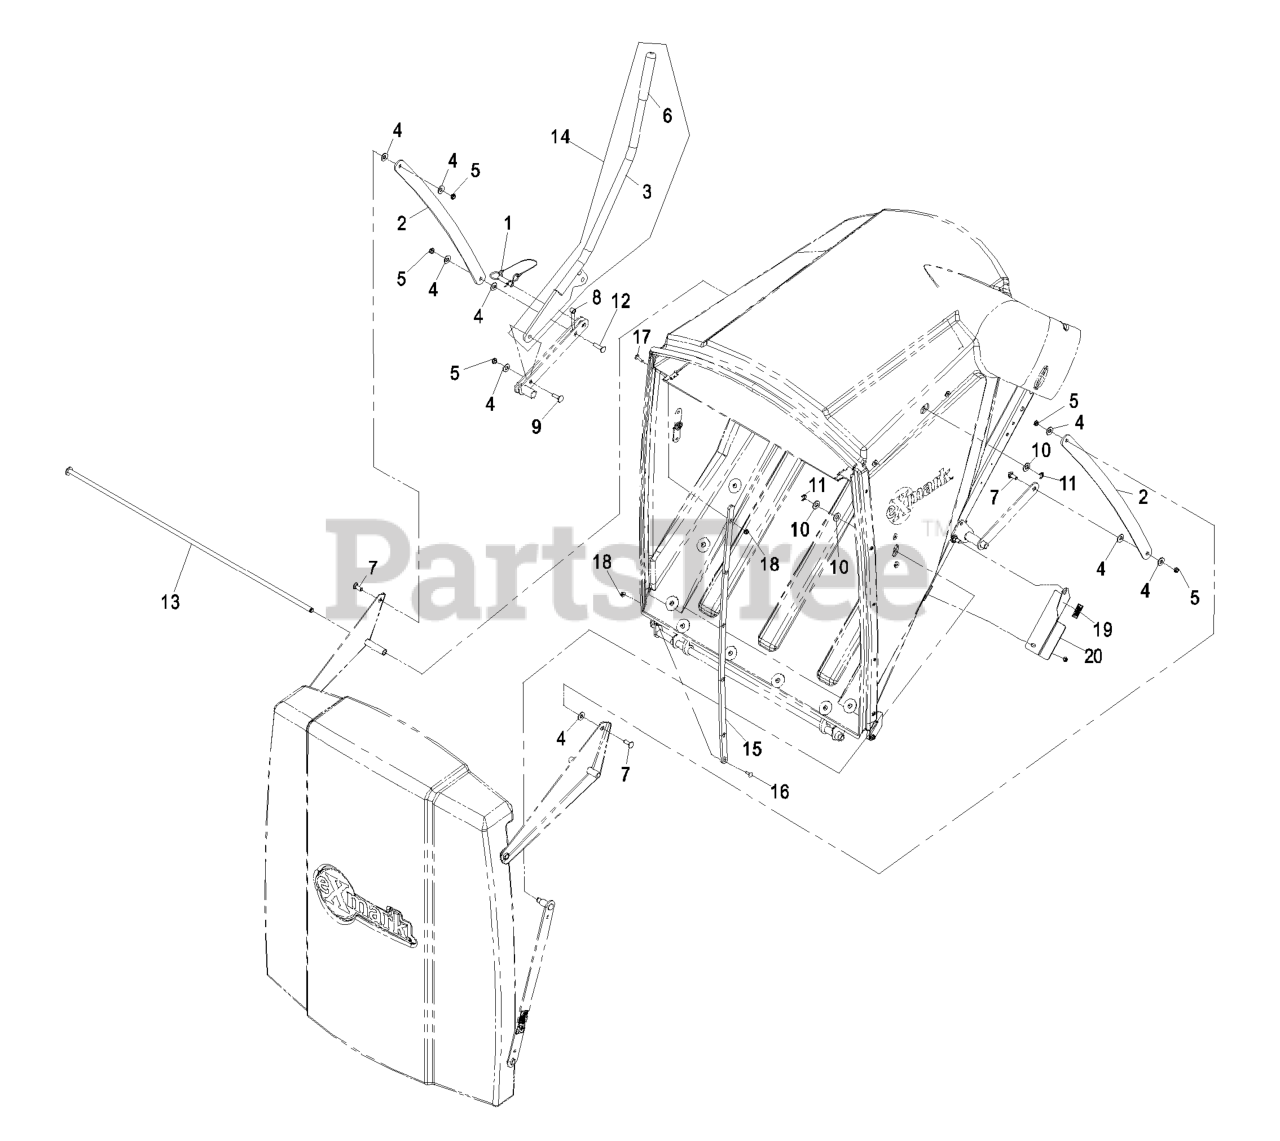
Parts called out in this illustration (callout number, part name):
1	PIN-HITCH (W/LANYARD)
4	WASHER-FLAT
6	HANDLE-GRIP
7	SCREW-CARR
8	BUSHING
9	BOLT-CARR
10	WASHER-FLAT
11	RING-RETAINING, EXTERNAL
12	SCREW-CARR
13	PIN,FR UPR DOOR PVT (PLTD
14	ASM,FRUVD DR HNDL WITH GR
16	BOLT-CARR
17	SCREW-TTH
19	DECAL-CAUTION
20	ASM,FRUVD MFLR SHLD AND D
